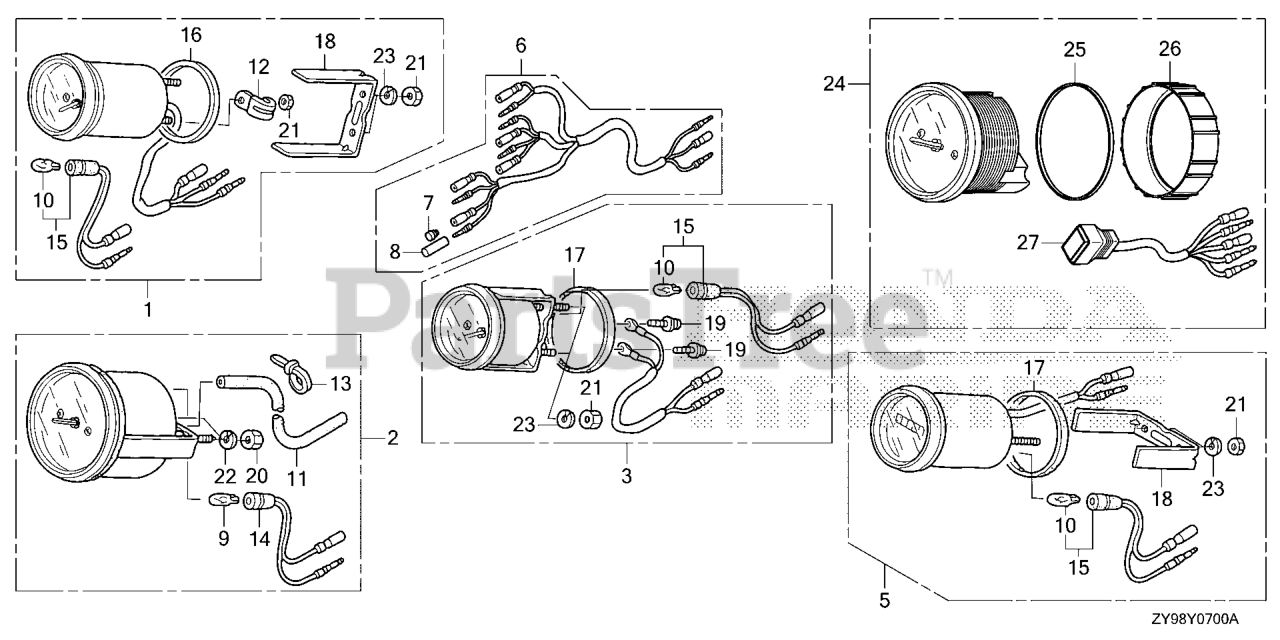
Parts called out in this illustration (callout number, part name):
1	METER KIT, TRIM (WHITE)
1	TRIM METER KIT
2	SPEEDOMETER KIT (WHITE)
2	SPEEDOMETER KIT *NHA85* (B) (BLACK)
3	METER KIT, VOLT (WHITE)
3	VOLT METER KIT
3	METER KIT, VOLT *NHA85* (B) (BLACK)
4	METER KIT, TACHO
4	METER KIT, TACHO (B)
5	HOUR METER KIT
6	HARNESS ASSY., METER (B)
7	PLUG, CONNECTOR (INNER) (TROLLING CONTROL)
8	PLUG, CONNECTOR (OUTER) (ENGINE NO.)
9	BULB, WEDGE BASE (T10) (12V 1.7W) (STANLEY)
10	BULB, WEDGE BASE (12V1.7W) (TOSHIBA)
11	TUBE, SPEED METER (4X7X8000)
12	CLAMP
13	BAND, SELF-LOCK
15	SOCKET
16	GASKET (TO 1015209) (FROM 1015210)
17	GASKET
18	BRACKET (TO 1015209) (FROM 1015210)
19	SCREW-WASHER (3X22)
21	NUT, HEX. (4MM)
23	WASHER, SPRING (4MM)
24	TACHO METER KIT
25	CUSHION RUBBER
26	RING
27	WIRE ASSY.
